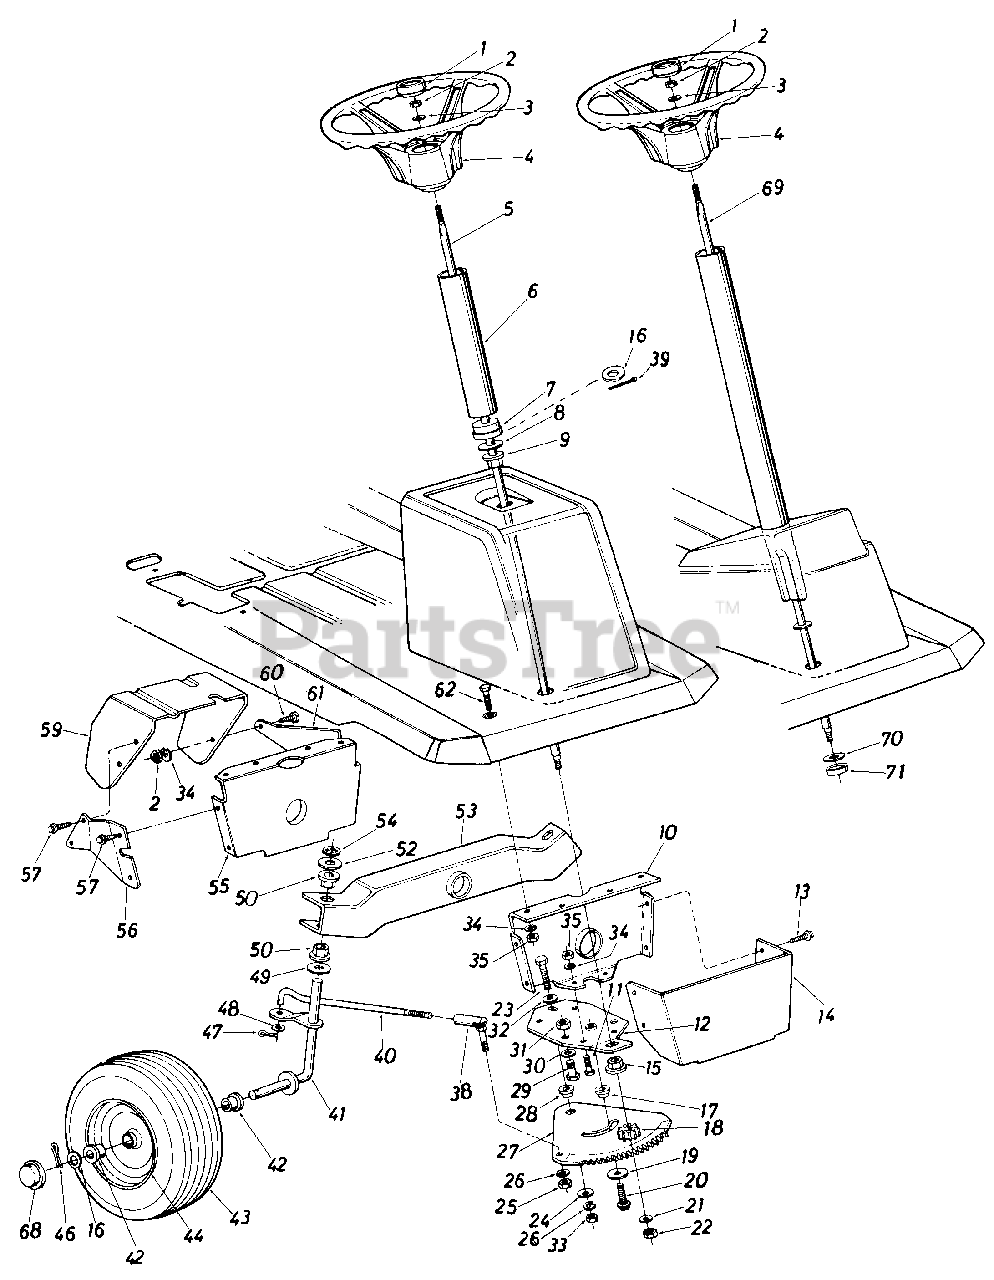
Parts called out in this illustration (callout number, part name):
1	Steering Wheel Cap
2	Hex Nut 5/16-18 Thd.*
3	Bell-Wash. .345" I.D. x .88" O.D.
4	Steering Wheel Ass'y.
5	Steering Shaft
8	Fl-Wash. .640" I.D. x 1.25" O.D.
9	Hex Flange Bearing
10	Pivot Bar Bracket
11	Hex Bolt 5/16-18 x .75" Lg.*
12	Steering Gear Support Brkt.
13	Hex Wash. Hd. AB-Tap Scr. 1/4 x.62" Lg.
16	Fl-Wash. .640" I.D. x 1.62" O.D.
17	Shoulder Spacer .622 Dia. x .218
18	Steering Pinion Gear
19	Fl-Wash. .385" I.D. x 1.38" O.D.
20	Hex Wash. Hd. Self-Tap Scr. 3/8-16 x 1.25" Lg.
21	Bell-Wash. .345" I.D. x .88" O.D.
22	Hex Nut 5/16-24 Thd.*
23	Hex Bolt 3/8-24 x 1.25" Lg. (Grade 5)
24	Fl-Wash. .385" I.D. x 1.38" O.D.
25	Hex Nut 3/8-24 Thd.*
26	L-Wash. 3/8" I.D.*
27	Steering Gear Segment
28	Shoulder Spacer .622" Dia. x .218
29	Hex Bolt (Nylon) 1/2-13 x .75" Lg.
30	Fl-Wash. .530" I.D. x .930" O.D.
31	Hex Nut 1/2-13 Thd.*
32	Bell-Wash. .385" I.D. x .88" O.D.
33	Hex Nut 3/8-24 Thd.
34	L-Wash. 5/16" I.D.
35	Hex Nut 5/16-18 Thd.
38	Ball Joint Ass'y. 3/8-24 Thd.
39	Cotter Pin 1/8" Dia. x 1.0" Lg.
40	Steering Tie Rod
41	Front Axle Ass'y.-R.H.
42	Flange Bearing .632" I.D.
43	Front Wheel Ass'y. Comp.
44	Front Wheel Rim Only
46	Cotter Pin 1/8" Dia. x 1.25" Lg.*
47	Cotter Pin 1/8" Dia. x 1.00" Lg.*
48	Fl-Wash. .385" I.D. x .87" O.D.
49	Fl-Wash. .635" I.D. x 1.12" O.D.
50	Hex Flange Bearing
52	Fl-Wash. .635" I.D. x 1.12" O.D.
53	Pivot Bar Ass'y.
54	Speed Nut 5/8" I.D.
55	Pivot Bar Bracket
56	Bracket Reinforcement-R.H.
57	Hex Wash. Hd. AB-Tap Scr. 1/4 x.62" Lg.
59	Clutch-Brake Pedal Ass'y.
60	Hex Bolt 5/16-18 x .75" Lg.
61	Bracket Reinforcement-L.H.
62	Hex Bolt 5/16-18 x .75" Lg.
68	Plastic Hub Cap
69	Steering Shaft Ass'y.
70	Fl-Wash. .62" I.D. x 1.50" O.D.
71	Spacer (Plastic)
